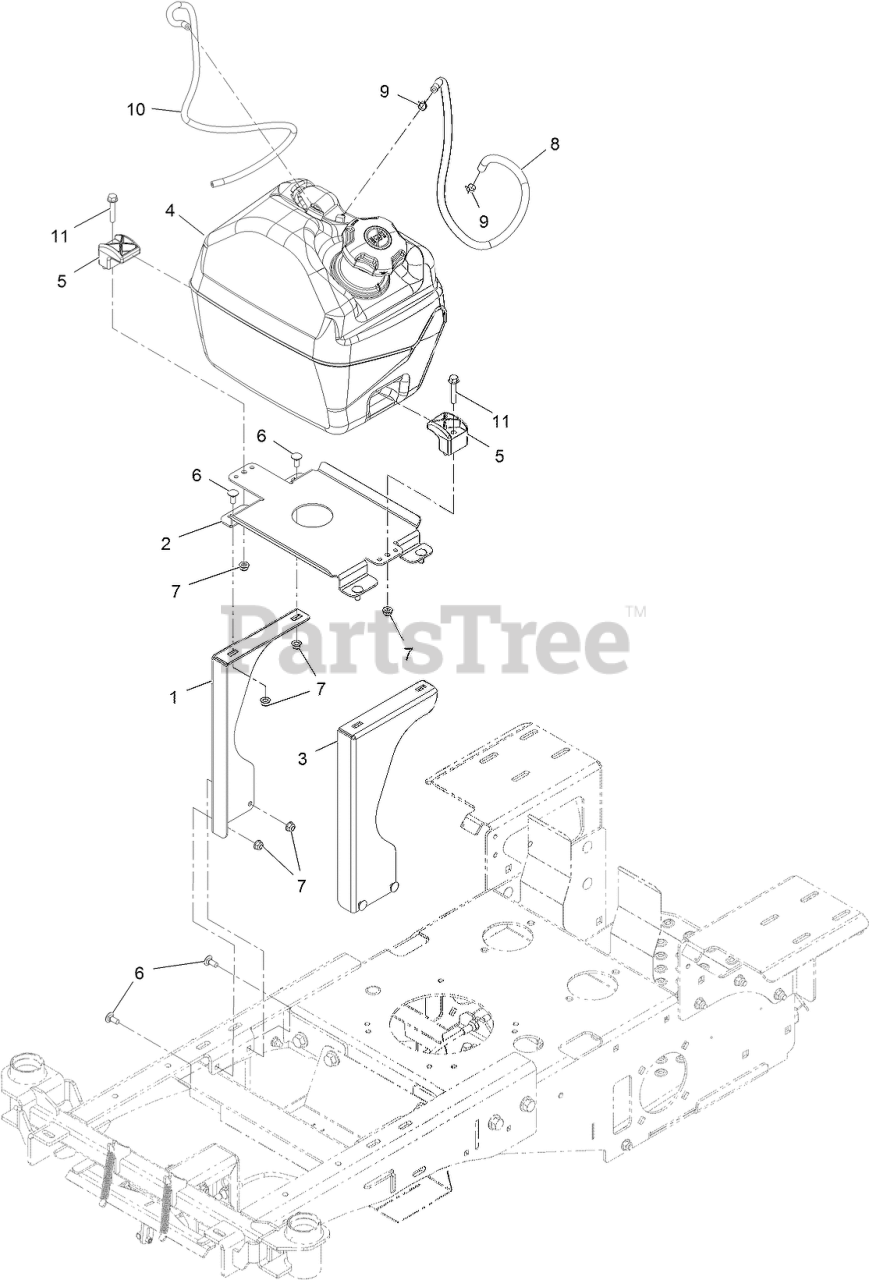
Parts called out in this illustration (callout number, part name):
1	PANEL, PLATFORM, FUEL TANK, JR36
2	SUPPORT-FUEL TANK
3	PANEL, PLATFORM, FUEL TANK, JR36, SS,.12
4	Fuel Tank ASM, 5 Gal
6	SCREW-CARR
7	Nut-Hex Flange
8	HOSE-FUEL
9	CLAMP-HOSE
10	HOSE-FUEL
11	Screw-HHF
